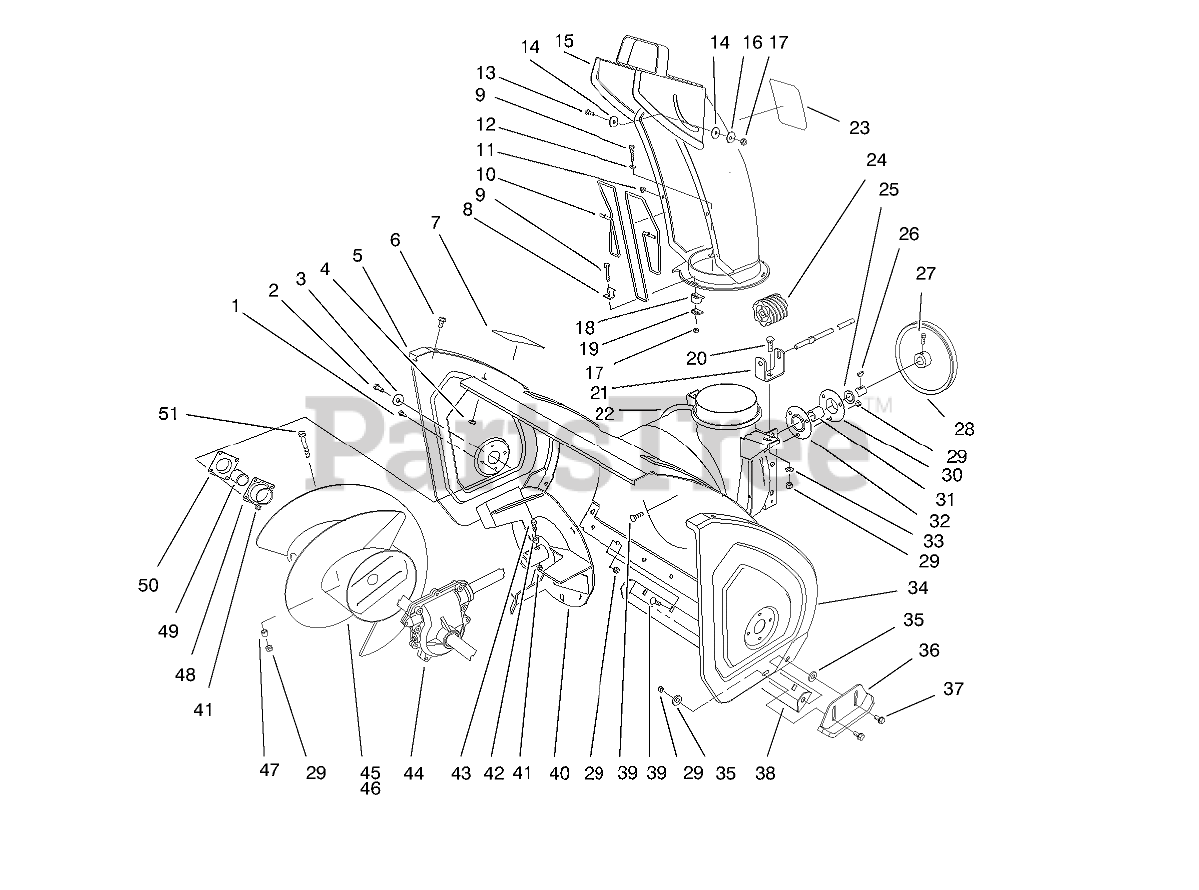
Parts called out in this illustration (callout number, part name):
1	SCREW-HH
2	SCREW-HH
3	WASHER
4	NUT-LOCK, NI
5	Plate-Side
6	SCREW-HHF
7	Decal-Warning (Only On: 38083)
7	Decal-Warning (Only On: 38084)
8	CLIP-GUARD, CHUTE
9	SCREW-HSH
10	GUARD-CHUTE
11	NUT-PUSH
12	WASHER-FLAT
14	WASHER-PLASTIC
15	ASM-Chute (Only On: 38083)
15	ASM-Chute (Only On: 38084)
16	WASHER-FLAT
17	NUT-LOCK, NI
18	RETAINER-CHUTE
19	PLATE-RETAINER, CHUTE
20	BOLT-CARR
21	BRACKET-WORM, CHUTE
22	ASM-Housing (Only On: 38083)
22	ASM-Housing (Only On: 38084)
23	Decal-Danger (Only On: 38084)
23	Decal-Danger (Only On: 38083)
24	GEAR-WORM
25	WASHER-THRUST
26	KEY-WOODRUFF
27	SCREW-SET, SQH
28	PULLEY-IMPELLER
29	NUT-LOCK, NI
30	FLANGE-CUP, BEARING
31	BEARING-BALL
32	FLANGE-CUP, BEARING
33	WASHER-PLAIN
34	Plate-Side
35	WASHER
36	Skid
37	SCREW-HHF
38	Blade-Scraper
39	SCREW-CARR
40	Impeller
41	NUT-LOCK, NI
42	SPACER
43	SCREW-HHF
44	AUGER GEARCASE ASM
45	Auger-RH (Only On: 38083)
45	Auger-RH (Only On: 38084)
46	Auger-LH (Only On: 38083)
46	Auger-LH (Only On: 38084)
47	SPACER-HUB, AUGER
48	BEARING-FLANGE, FRONT
49	BEARING
50	BEARING-FLANGE, REAR
51	SCREW-HH
